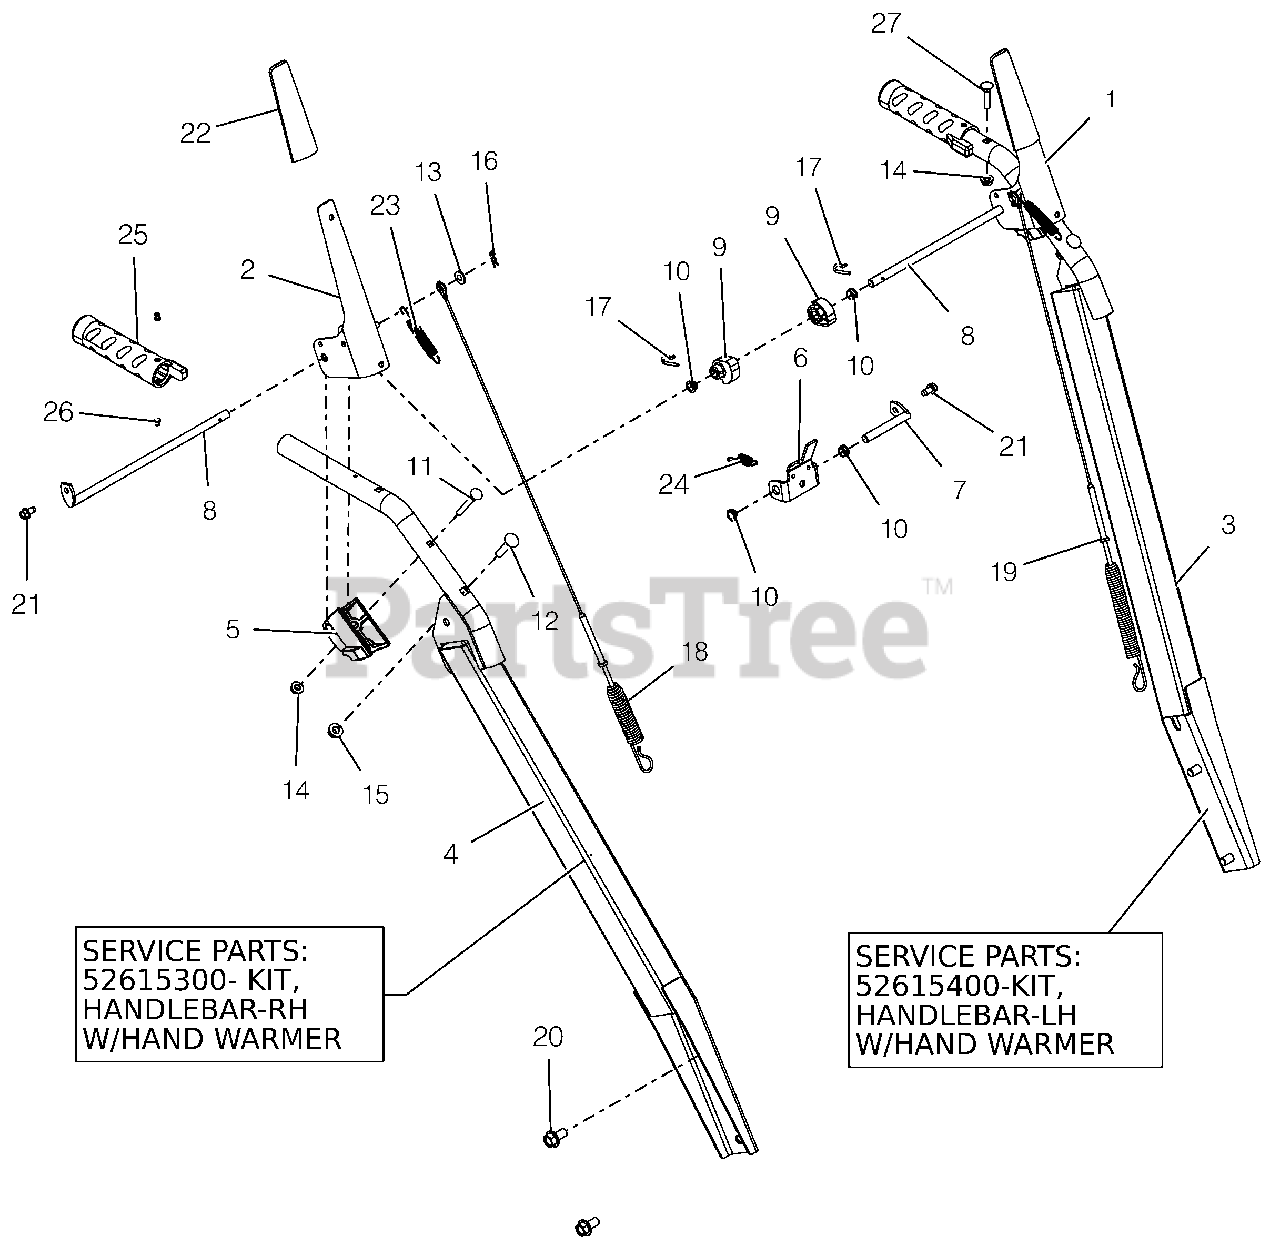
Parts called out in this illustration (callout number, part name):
1	LEVER, CLUTCH-LH
2	LEVER, CLUTCH-RH
3	HANDLEBAR, HEAVYDUTY-PRO LH
3	KIT, HANDLEBAR-LH W/WARM GRIP
4	HANDLEBAR, HEAVYDUTY-PRO-RH
4	KIT, HANDLEBAR-RH W/WARM GRIP
5	BLOCK, CLUTCH PADDLE
6	BRACKET, INTERLOCK ARM
7	ROD, INTERLOCK PIVOT
8	ROD, PADDLE MOUNT - PRO
9	CAM, INTERLOCK
10	BUSHING, POLYLINER-.38 SNAPIN
11	BLT-RDHDXLSQNK .25-20X2.0 G5YZ
12	@BLT-RDHDSQNK .31-18X1.50 G5YZ
13	@WSHR-FL-STL.281X.62X.065 YWZC
14	NUT-LK-CTR-FLG .25-20 YWZC
15	@NUT-LK-TOP-FLG .31-18 YWZC
16	PIN-HAIR INT .06X.18X.77
17	PIN, SPRING CLIP
18	CABLE, AUGER (DELUXE & PRO)
19	CABLE, UPPER TRACTION
20	BLT-SERHFWH .38-16X.75 YWZC
21	SCR-TAP .25-20X.50 HWH TR YWZ
22	SLEEVE, CLUTCH PADDLE-GRAY
23	SPRING, EXTENSION
24	SPRING-EXT .047X.438X1.45
25	GRIP,HEATED HANDLE-GRAY
26	RVT-POP #43 .125X.313 STL ZINC
27	BLT-RDHDXLSQNK.25-20X1.25 G5ZC
